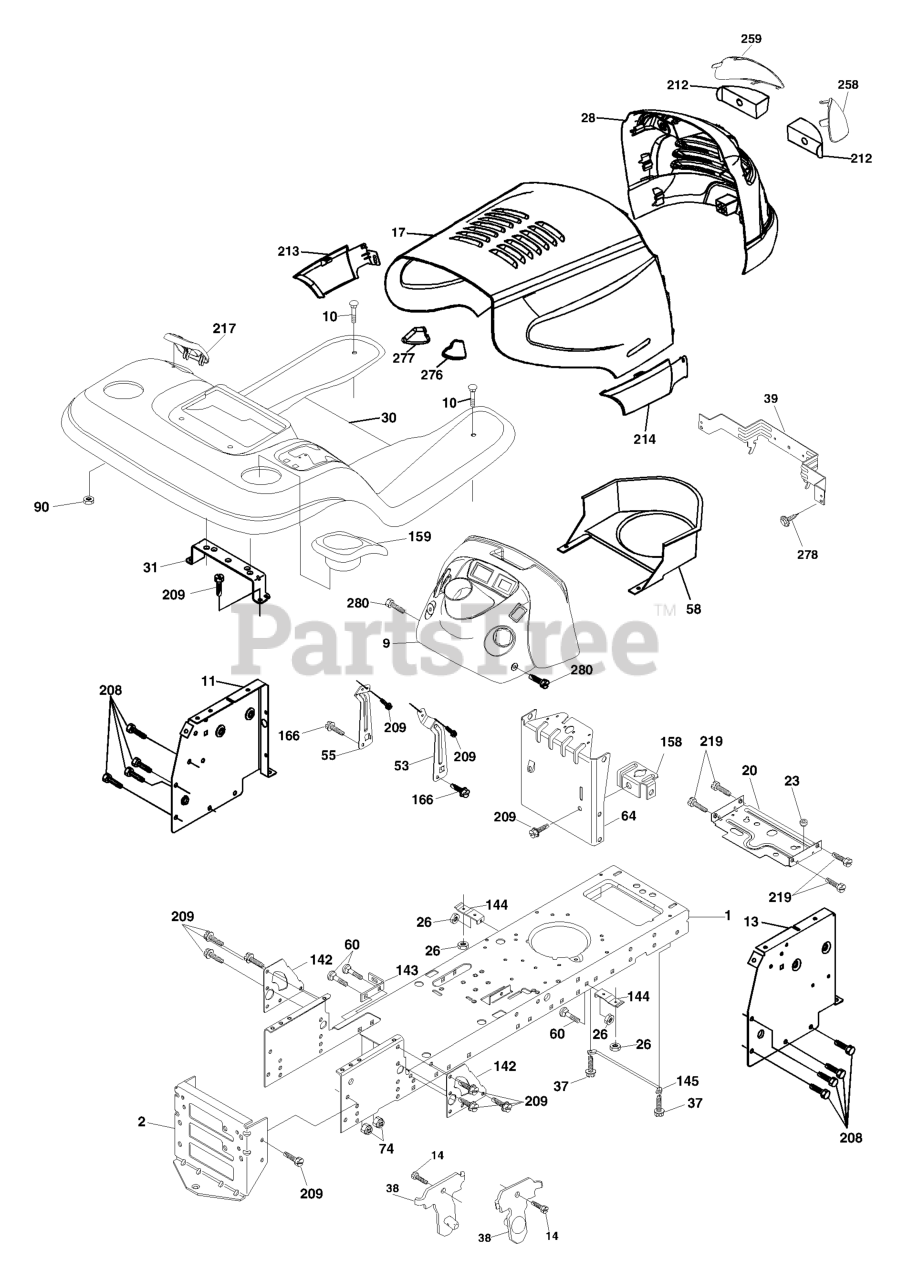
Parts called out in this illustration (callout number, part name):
1	CHASSIS STAMPING
2	DRAWBAR, 12GA
9	DASH.NON-TEX.GRAY
10	BOLT D
11	PANEL.DASH.LH.LTX
13	PANEL DASH RH
14	SCREW LT
17	HOOD
20	PLATE MTG.BATTERY/FUEL TANK
23	BUSHING.SNAP.NYL.BLK.
26	NUT
28	GRILL/LENS ASSY ( YT MODEL)
30	FENDER
31	BRACKET.SUPPORT.FENDER
37	Screw Thdrol 5/16-18 x 1/2 TYT
38	BRACKET.ASM.PIVOT.MOWER.REAR
39	BRACKET PIVOT LASER
53	BRACKET DASH RH
55	BRACKET DASH LH
58	AIR DUCT ENGINE
60	Bolt Rdhd Sqnk 3/8-16 unc x 3/4
64	DASH LOWER
90	NUT.PUSH.3/16
142	PLATE REINFORCEMENT
143	BRACKET, SWAYBAR CHASSIS
144	BRKT, FOOT REST
145	ROD PIVOT CHASSIS/HOOD
158	BRACKET PARKING BRAKE
159	GREY CUP HOLDER
166	SCREW
208	SCREW 3/8-16X1/2
209	SCREW, 3/8-16X3/4
212	INSERT LENS
213	SKIRT SIDE LH
214	SKIRT SIDE RH
217	CONSOLE FUEL WINDOW
219	SCREW
258	LENS ELITE CLEAR RH
259	LENS ELITE CLEAR LH
276	BUMPER HOOD RH
277	BUMPER HOOD LH
278	SCREW
280	SCREW THDROL 3/8-16 X 1-1/2
